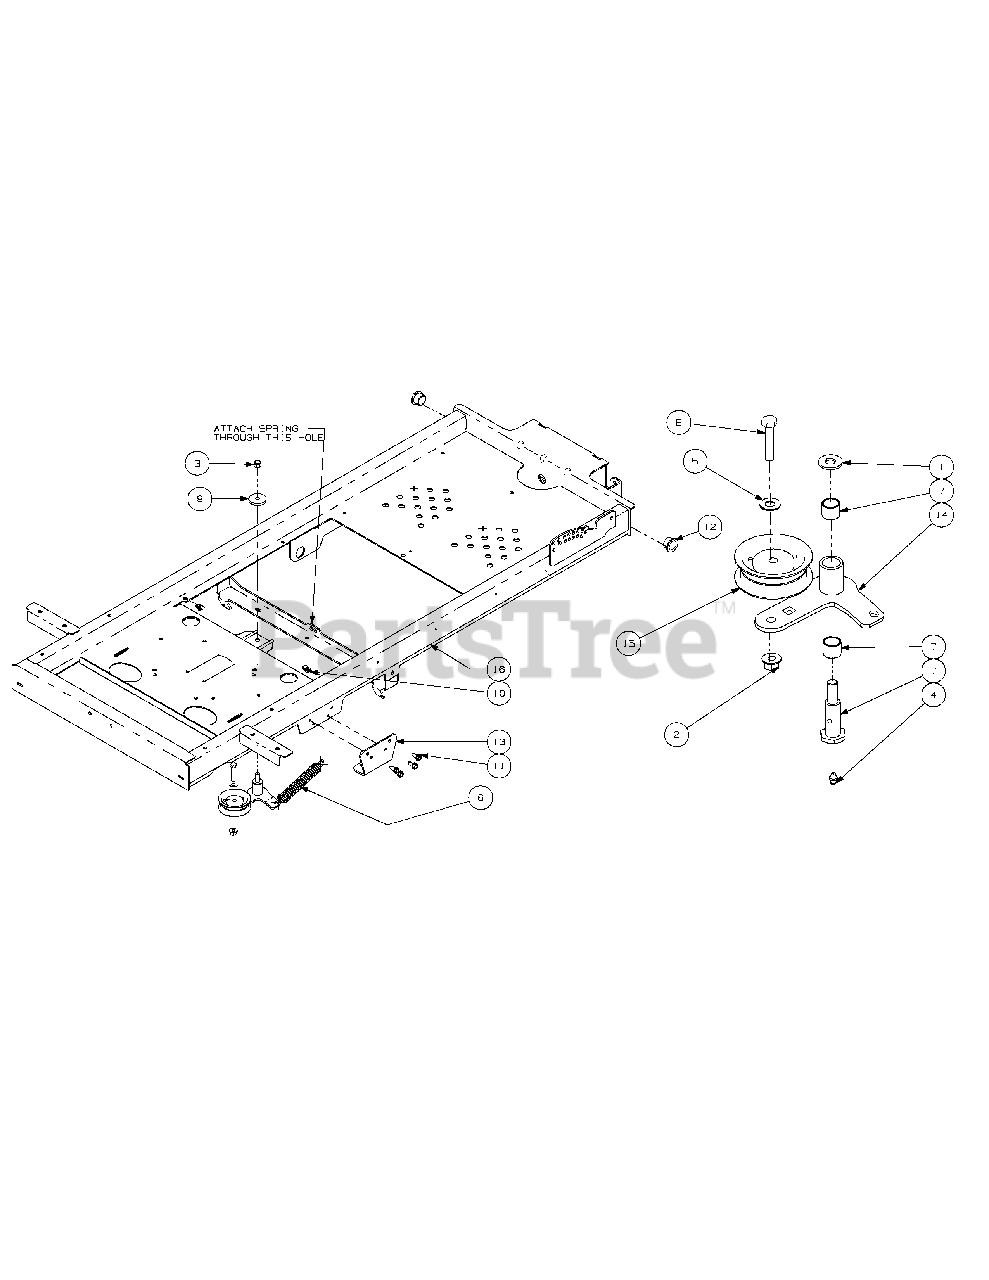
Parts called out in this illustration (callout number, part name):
1	Flat Washer, 3/8 zinc
2	Hex Nut, 3/8-16 Flange Lock
3	Nylock Nut, 7/16-14
4	Grease Fitting, 1/4-28 x 3/16
5	Washer, 3/8, SS
6	Extension Spring, 1.00 OD x 5.00 lg
7	Shoulder Bolt
8	Hex Cap Screw, 3/8-16 x 1-3/4
9	Flat Washer, 7/16 ID x 1.75 OD
10	U-Nut, 1/4-20
11	Self Tapping Screw 5/16-18 x .750
12	Bronze Bushing, 1.00 ID x 1.50 OD
13	Transmission Mounting Bracket
14	Idler Arm Assembly includes:
15	Flat Idler Pully
16	Frame Assembly Weldment
